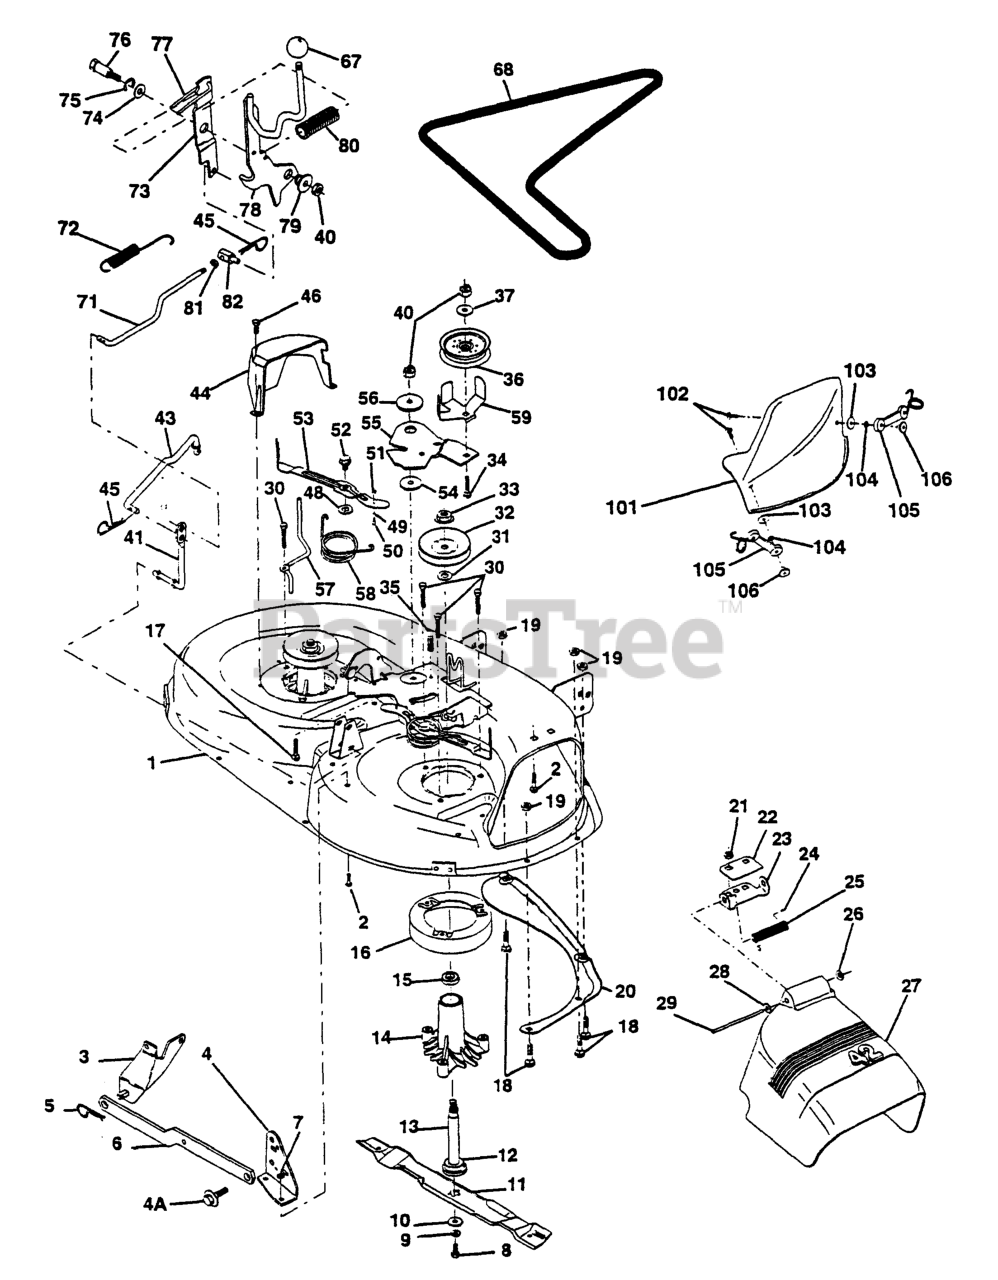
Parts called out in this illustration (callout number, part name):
1	DECK ASM MWR 42"
2	RP BOLT 5/16-18 X3/4 ZN/YEL GR
3	BRKT ASM SWAY BAR
4	BRKT DECK SW BAR
4A	BOLT SHD 5/16-18
5	RETAINER-SPRNG RB
6	REAR SUSP ARM
7	NUT.71038.31-18.HEX.NYLOCK
8	BLADE BOLT
9	LOCKWASHER
10	WASHER.BLADE
11	BLADE.42".MULCH
12	BEARING.BALL.#6204.(MANDREL)
13	SHAFT ASM VENT
14	HOUSING.MANDREL.VENTED (MACHD)
16	STRIPPER
17	BOLT
18	BOLT
19	NUT.71038.31-18.HEX.NYLOCK
20	BAFFLE
21	NUT.71038.31-18.HEX.NYLOCK
22	STIFFENER BRACKET
23	DEFLECTOR BRACKET
24	CAP-SLEEVE LT
25	SPRING TORSION
26	NUT PUSH M
27	SHIELD.DEFLECTOR.MOWER.42".BLK
28	Washer 11/32 X 5/8 X 16 Ga
29	ROD.HINGE
30	SCREW
31	WASHER
32	MANDREL PULLEY
33	NUT
35	FASTENER.XMAS.TREE
36	FLAT IDLER PULLEY
37	WASHER
40	NUT
43	CLUTCH ROD
44	GUARD MANDREL LH BLACK
45	RETAINER M
46	SCREW.1/4-20X5/8
49	CAM FOLLOWER
52	BOLT.SHOULDER.5/16-18
53	ARM
54	HARDENED WASHER
55	IDLER ARM
56	SPACER RETAINER
59	GUARD, BELT
67	KNOB T (1/2-HOLE)
68	RP.V-BELT
71	CLUTCH ROD
72	RETURN SPRING
73	ARM CLUTCH SECONDARY
77	KEEPER SPRING
78	CLUTCH ARM
79	BUSHING.FLANGE.E-RING.GROOVE
80	SPRING
81	NUT
82	TRUNNION.ADJUSTABLE.3/8-16
101	COVER MULCH 42"
102	SCREW
104	LOCKWASHER #10
105	LATCH ASSEMBLY
106	WELDNUT
